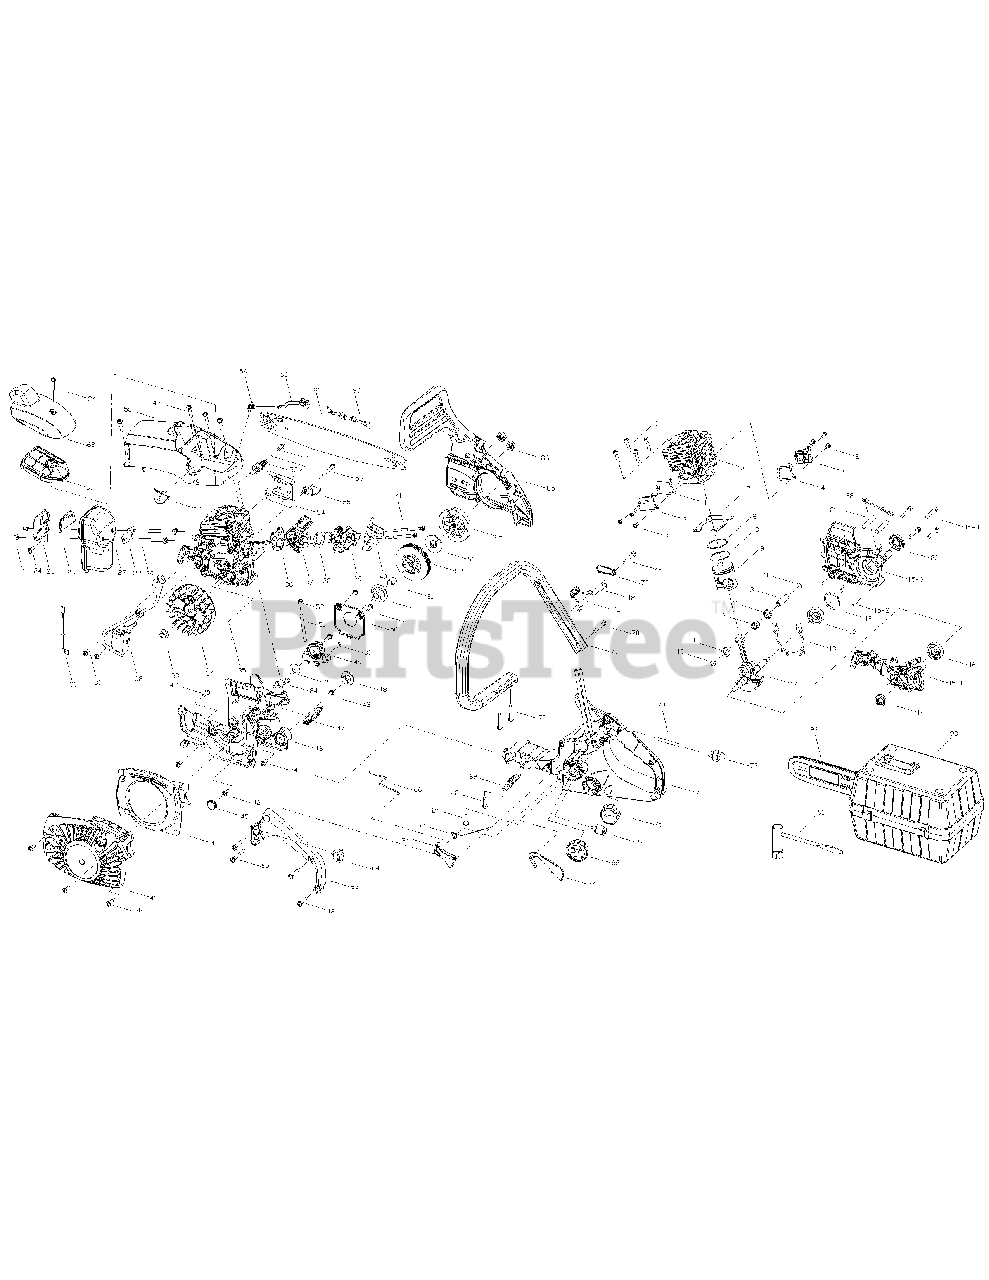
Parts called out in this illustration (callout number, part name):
8	PISTON RING
13	PIN, PISTON
15	CLY CASE ASSEMBLY
15-1	CLY CASE, LEFT
15-3	CLY CASE, RIGHT
17	CRANK/ROD ASSEMBLY
25	COVER, MESH
26	SPARK ARRESTER
27	MUFFLER ASSEMBLY
32	IGNITION ASSEMBLY
33	NUT
34	FLYWHEEL ASSEMBLY
35	WOODRUFF KEY
37	ISOLATER ASSEMBLY , CARB.
39	CARBURETER
40	AIR GUIDE
42	SCREW
43	STARTER HOUSING ASSEMBLY
44	CAP, AIRWAY
45	CAP, RUBBER
46	BRACKET ASSEMBLY
47	FIXED, PUSH ROD
48	CAP, RUBBER
49	PUMP ASSEMBLY
50	CAP, ANTI-DUST
52	CONNECTOR
53	SPARK PLUG
55	CHAIN CATCH
57	CAP, ADJUST
59	HOLDER, CHOKE LEVER
60	LEVER, CHOKE
61	AIR FILTER ASS.Y
62	TOP COVER
63	HANDLE, LB
67	TRIGGER, THROTTLE
71	HANDLE, FRONT
73	CAP, SPRING
74	TRIGGER, RELEASE
75	OIL CAP ASSEMBLY
76	HANDLE ASSEMBLY (R)
82	DRUM ASSEMBLY
84	CLUTCH ASSEMBLY
85	BRAKE KIT ASSEMBLY
87	FUEL FILTER
88	FUEL CAP ASSEMBLY
93	CARRY CASE
